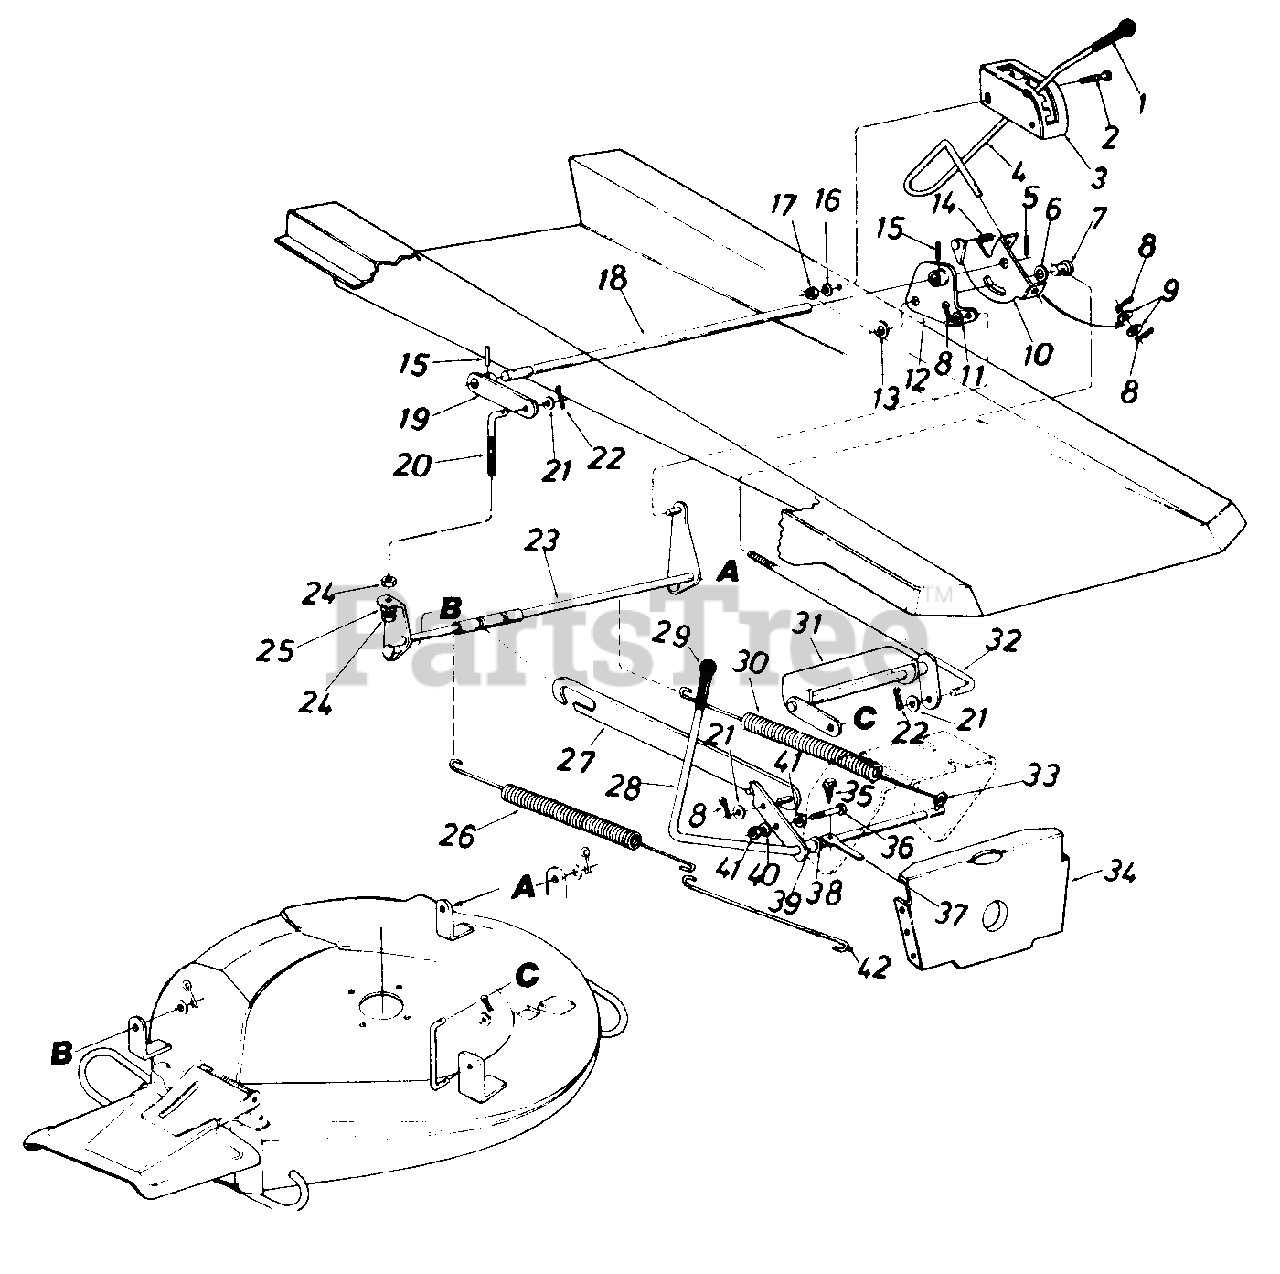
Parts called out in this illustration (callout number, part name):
2	Truss Mach. Scr. 5/16-18 x .75" Lg.
5	Spring Pin Spir. 3/16" Dia. x 1.50" Lg.
6	Fl-Wash. .385" I.D. x .87" O.D.
7	Adj. Ferrule Deck Lift Handle
8	Cotter Pin 1/8" Dia. x 1.00" Lg.
9	Fl-Wash. .531" I.D. x .930" O.D.
10	Deck Lift Handle Retainer Ass'y.
11	Fl-Wash. .385" I.D. x .87" O.D.
12	Deck Lift Brkt. Ass'y.-L.H.
13	Fl-Wash. .635" I.D. x 1.04" O.D.
14	Compression Spring .50" Dia. x 1.0" Lg.
15	Spring Pin Spir. 1/4" Dia. x 1.50" Lg.
16	L-Wash. 5/16" I.D.
17	Hex Nut 5/16-18 Thd.
18	Rear Hgt. Adj. Shaft
19	Deck Lift Brkt. Ass'y.-R.H.
20	Deck Adj. Scr. 3/8-16 Thd.
21	Fl-Wash. .385" I.D. x .87" O.D.
22	Intern. Cotter Pin 1/2" Dia.
23	Deck Link Ass'y.-Rear
24	Hex Nut 3/8-16 Thd.
25	L-Wash. 3/8" I.D.
26	Extension Spring .73" O.D. x 1 3.84" Lg.
27	Deck Drive Control Bracket
28	Blade Engagement Lever Ass'y.
30	Extension Spring .73" O.D. x 13.89" Lg.
31	Deck Lift Ass'y.-Front
32	Deck Lift Connecting Rod
33	Clevis Pin Special .250" Dia.
34	Pivot Bar Bracket
35	Hex TT-Tap Scr. 1/4-20 x .75" Lg.
36	Hex Bolt 5/16-18 x 1.50" Lg. (Grade 5)
37	Switch Actuator
38	Fl-Wash. .531" I.D. x .930" O.D.
39	Spacer .511" I.D. x .70" O.D. x.38" Lg.
40	L-Wash. 5/16" I.D.
41	Hex Nut 5/16-18 Thd.
42	Spring Hook
